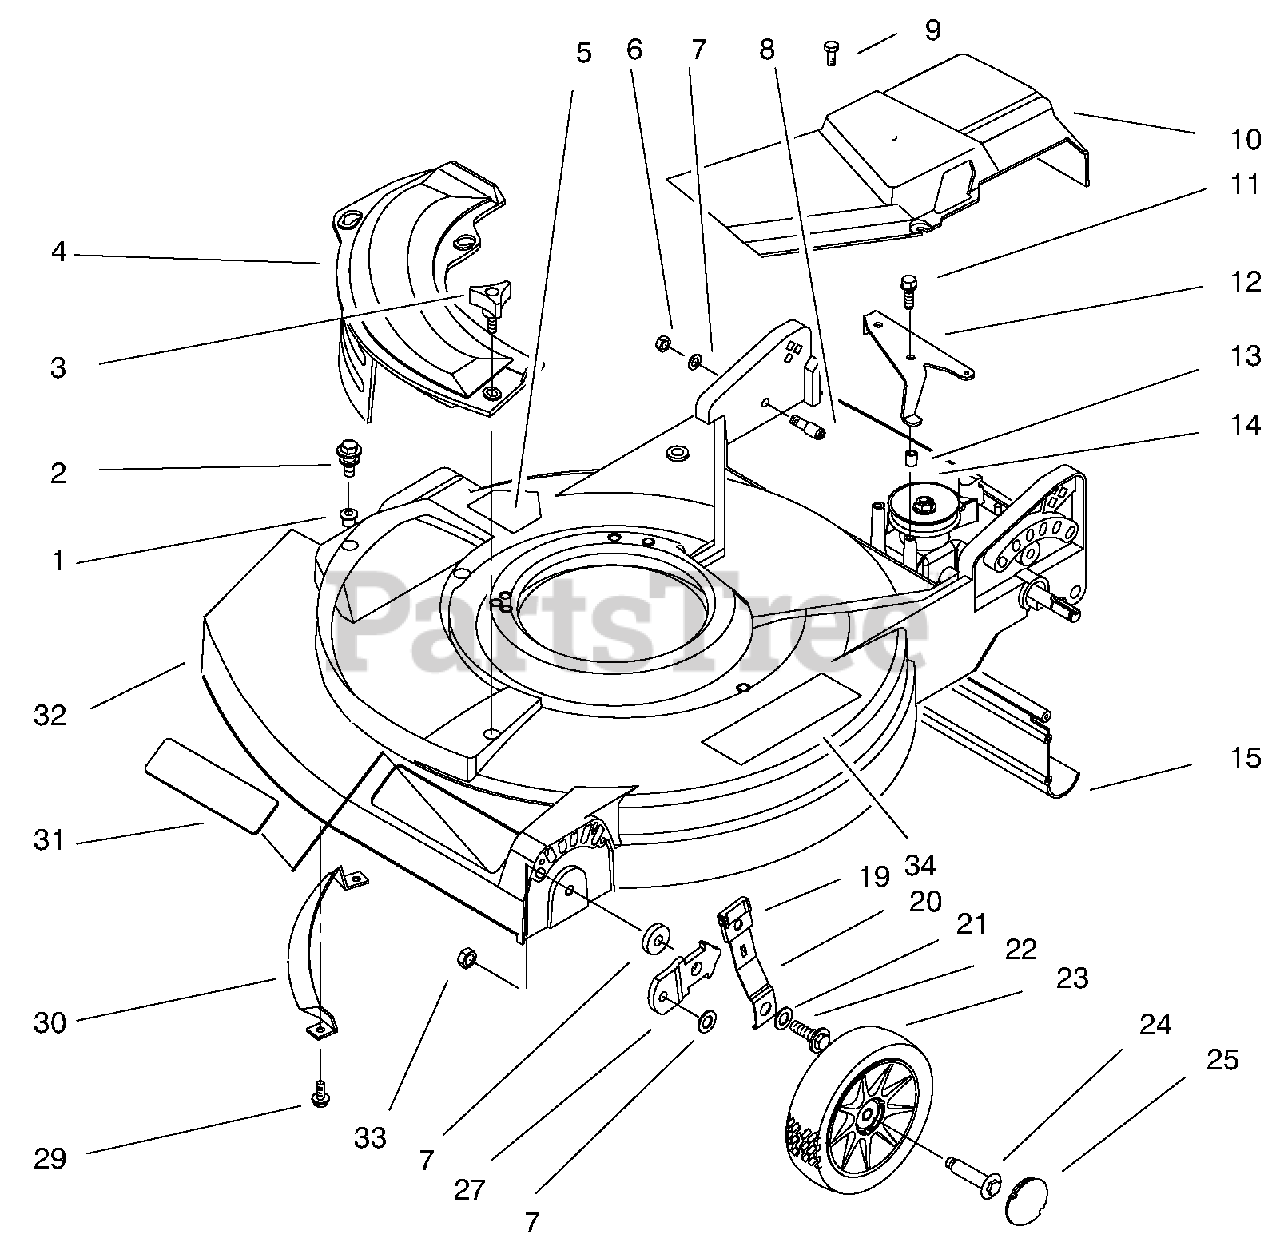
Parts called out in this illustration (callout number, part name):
2	Screw-Thread Forming
3	Knob
4	Cover- Plate, Mulch
5	Decal-Danger (English)
7	Washer-Wheel Bolt
8	Bolt-Shoulder
10	Cover-Drive
11	Screw
12	Bracket-Actuator
14	Gear Case Assembly
15	Shield-Trailing
19	Knob-Spring Arm
20	Spring Arm Assembly
21	Washer-Belleville
22	Bolt-Shoulder
23	Wheel-6"
24	Bolt-Wheel
27	Bracket-H. O. C.
30	Bar-Toe
32	Housing-21 (Incl. Ref. #5 & 34)
33	Nut-Lock
34	Decal-Warning
